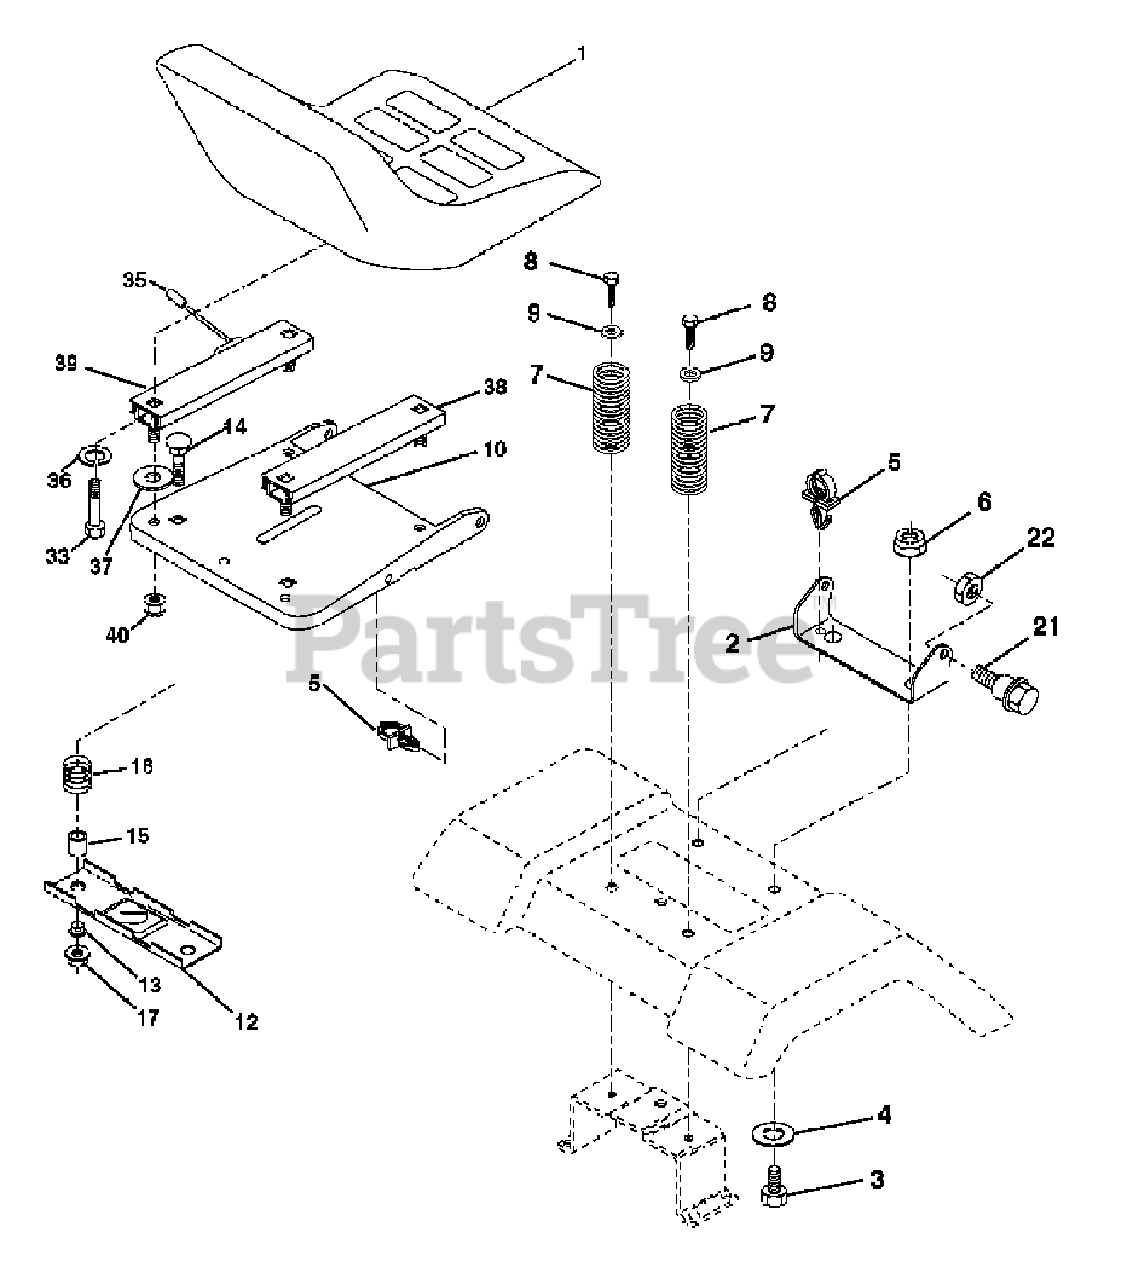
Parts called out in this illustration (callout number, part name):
1	Seat
2	Bracket Pivot Seat 8 720
3	Bolt Fin Hex 3/8-16 x 1
4	Washer Flat 13/32 x 1.0 x 10 Ga.
5	Clip Push-In
6	Nut Hex w/Ins. 3/8-16 Unc
7	Spring Seat Cprsn 2 250 Blk Zi
8	Screw 3/8-16 x 1
9	Washer 13/32 x 1.0 x 14 Ga.
10	Pan Seat
12	Bracket Mounting Switch
13	Bushing Snap Blk Nyl 50 Id
14	Bolt Rdhd Sqnk 1/4-20x1-1/2
15	Spacer Split 28 x .88 Zinc
16	Spring Cprsn Plate
17	Nut Lock 1/4 Lge Flg Gr 5 Zinc
21	Bolt Shoulder 5/16-18 Unc
22	Nut Hex Lock W/Ins 5/16-18
33	Bolt Fin Hex 5/16-18 Unc x 3-1/4
35	Cap Vinyl Yellow
36	Washer Split
37	Washer 11/32 x 5/8 x 12 Ga.
38	Track Slide Seat RH
39	Track Slide Seat LH
40	Nut Crown Lock 5/16-18
